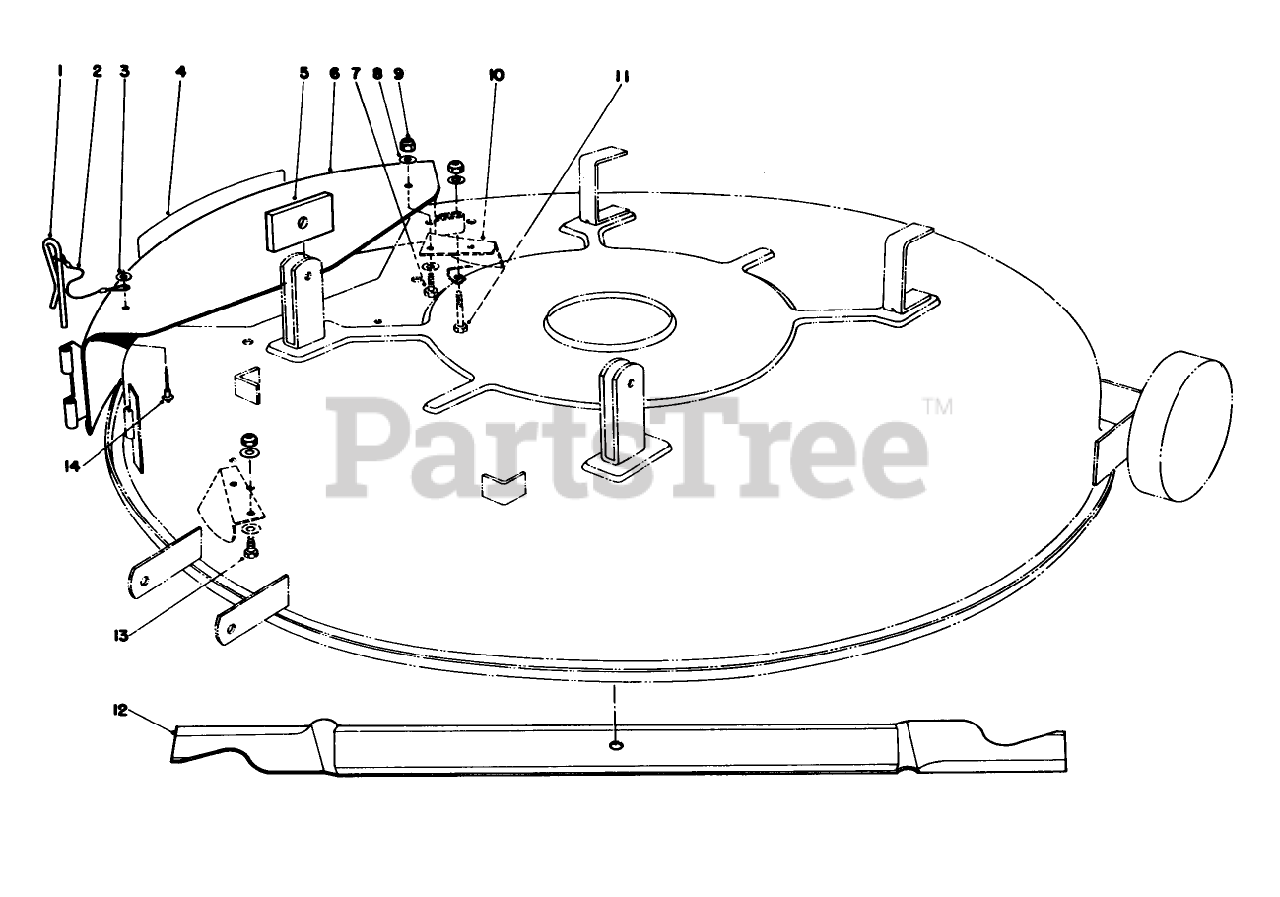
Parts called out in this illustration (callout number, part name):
1	PIN-LOCKING, CHUTE
2	LANYARD
3	WASHER-PLAIN
4	COVER DECAL
5	SPACER
6	Cover-Mulcher Assembly (Incl. Ref. #1-4 & 14)
7	SCREW-HH
8	WASHER-PLAIN
9	NUT-LOCK, NI
10	KICKER B
11	SCREW-HH
12	Blade
13	SCREW-HH
14	RIVET-BLIND
